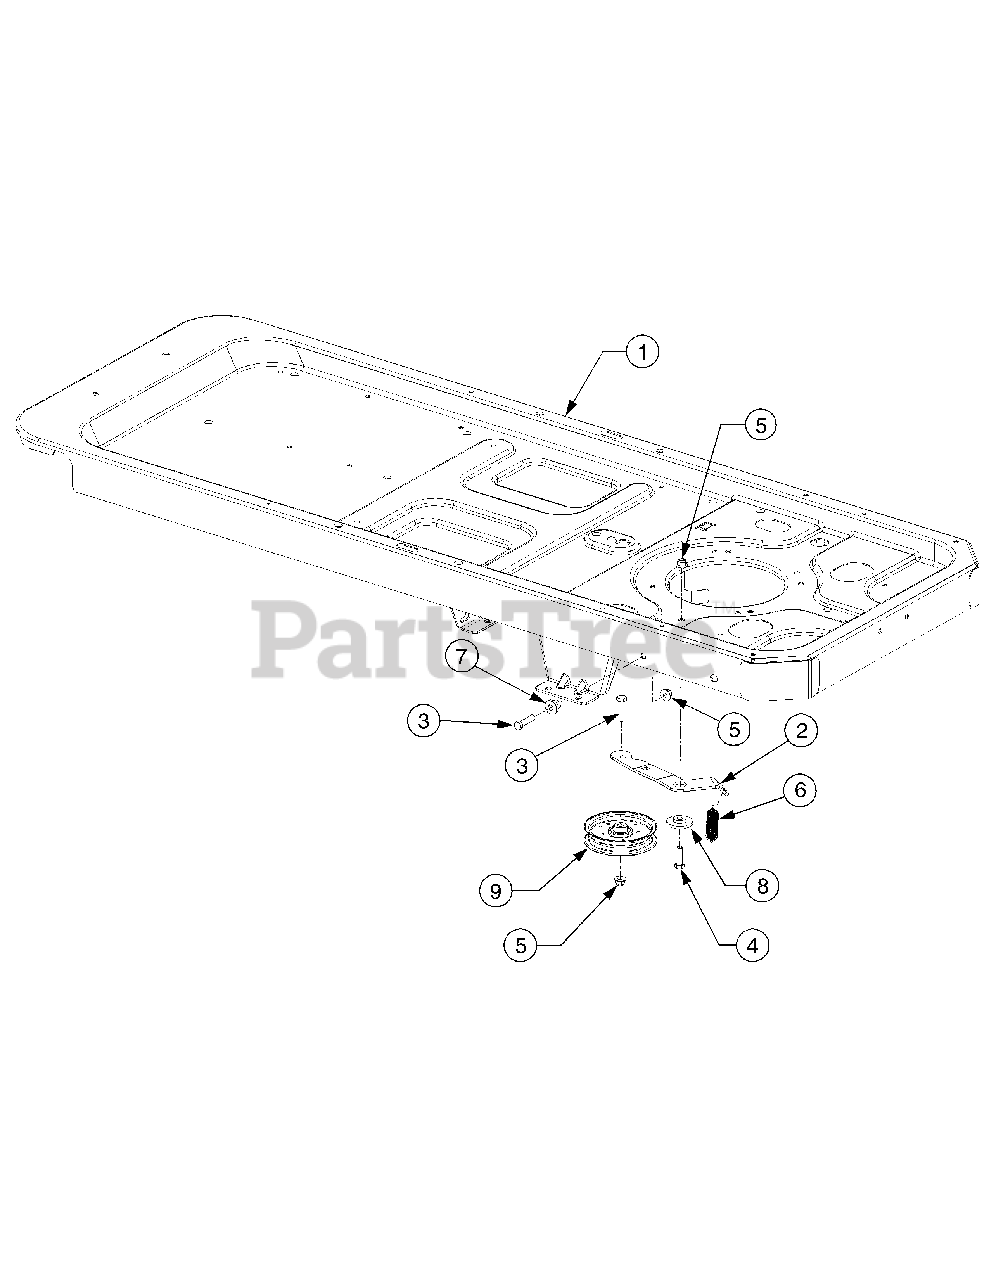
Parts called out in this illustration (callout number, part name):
3	Screw, Hex Cap, 3/8-16 x 1.5 GR5
4	Screw, Hex Cap, 3/8-16 x 1.25 GR5
5	Nut, Hx Insert Flange Lck, 3/-16 GRF
6	Spring, Extension, .75 x 5.06
7	Spacer, Shoulder, .39 x 1.0 x .7
8	Screw, Shoulder, .884 x .19
9	Pulley, Idler, 4.25 Dia.
